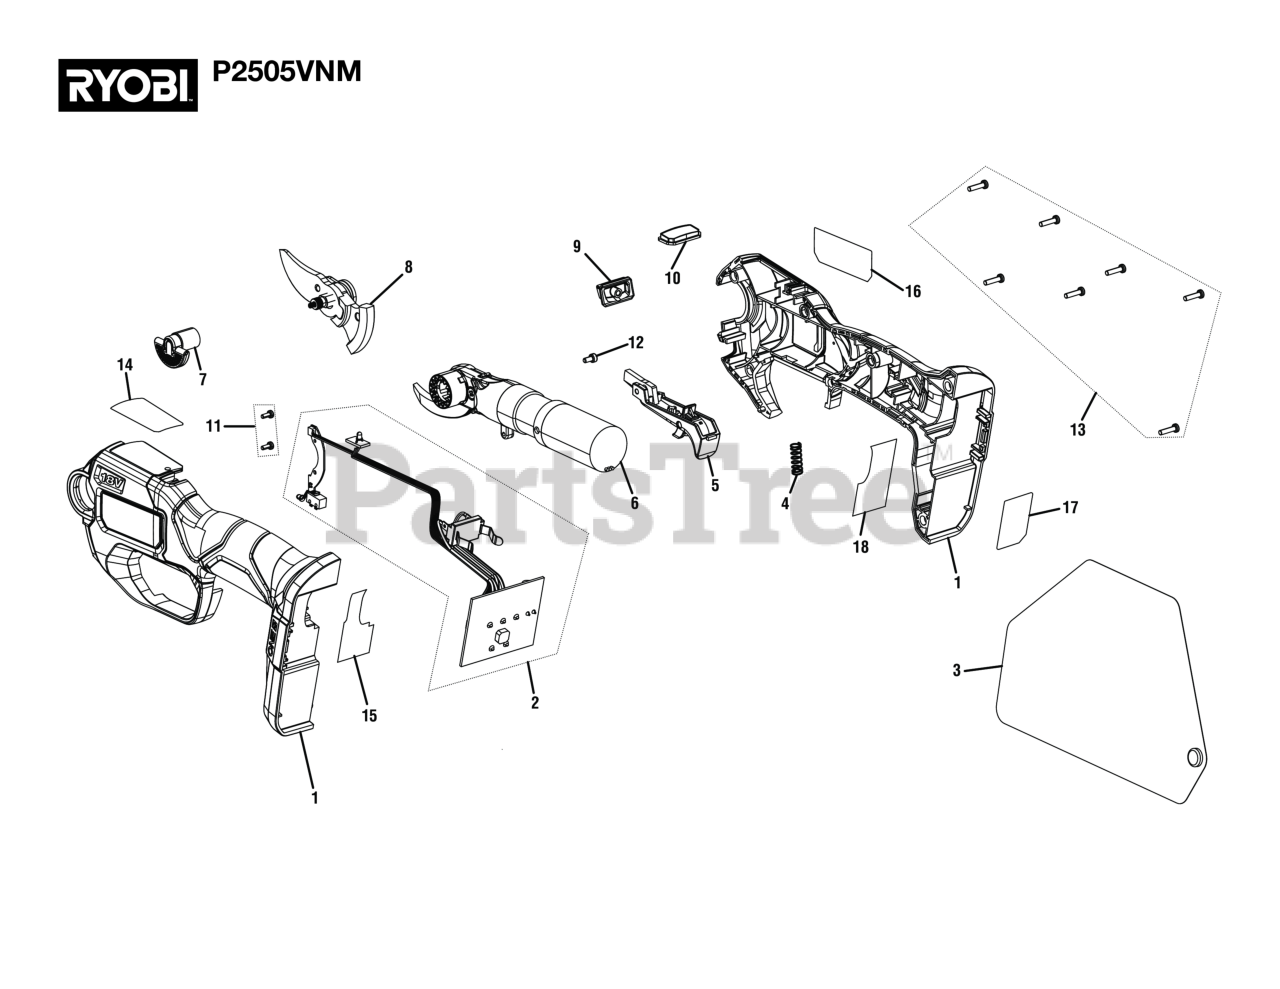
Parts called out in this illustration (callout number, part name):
1	Handle Assemby (Inc. Key Nos. 14-18)
2	Circuit Board Assmbly
3	Blade Sleeve
5	Trigger and Lock-Out Button Assembly
6	Motor and Gear Box Assembly
7	Knob Assembly
8	Blade Assembly
9	LED Cover
10	Logo Cover
11	Screw (M2.6 x 6 mm, T8 Torx Pan Hd.)
12	Screw (M3 x 5 mm, Hex. Soc. Cap Hd.).
13	Screw (M3 x 12 mm)
